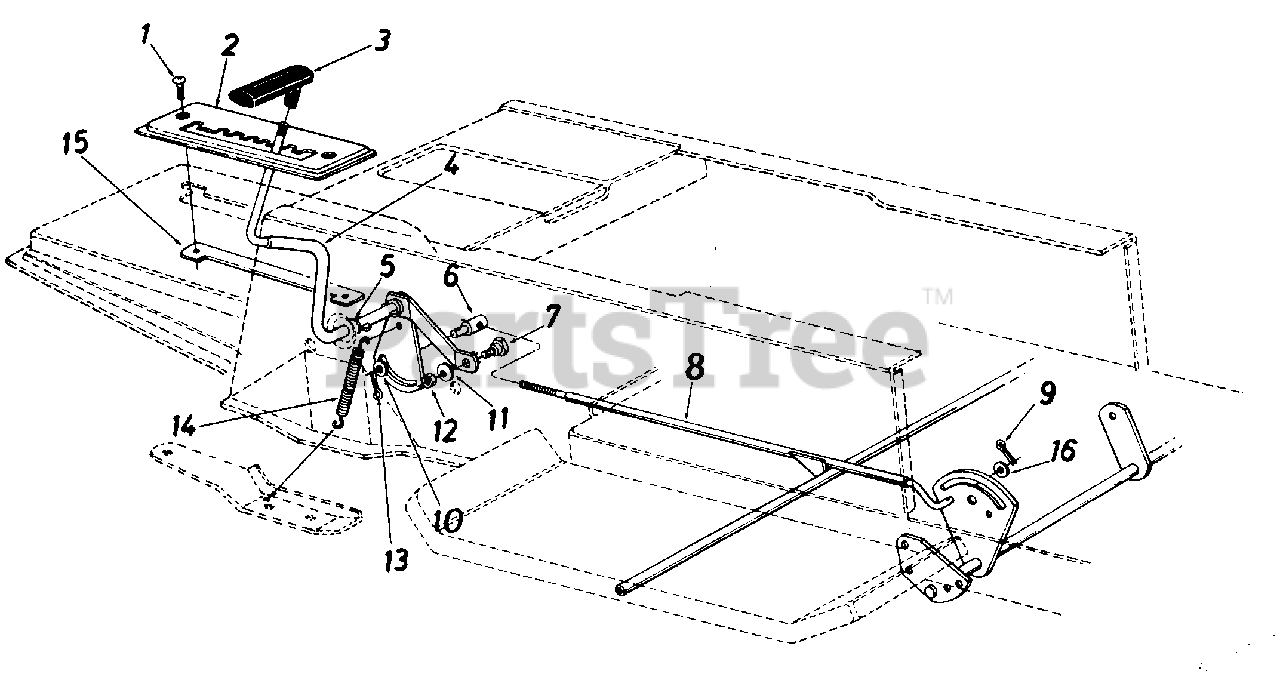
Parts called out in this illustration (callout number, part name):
1	Truss Mach. Scr. 1/4-20 x .75" Lg.
4	Speed Selector Cam Ass'y.
5	Flat Washer .53" I.D. x .93"
6	Ferrule 3/8-24 x .37" Dia.
7	Shoulder Bolt .435" Dia. x .160
8	Speed Control Rod Ass'y.
9	Cotter Pin 3/32" Dia. x .75"
10	Fl-Wash. .385" I.D. x .62" O.D.
11	L-Wash. 5/16" I.D.
12	Hex Nut 5/16-18 Thd.
13	Cotter Pin 3/32 Dia. x .75"
14	Spring
15	Clamping Plate
16	Fl-Wash. .47" I.D. x .88" O.D.
